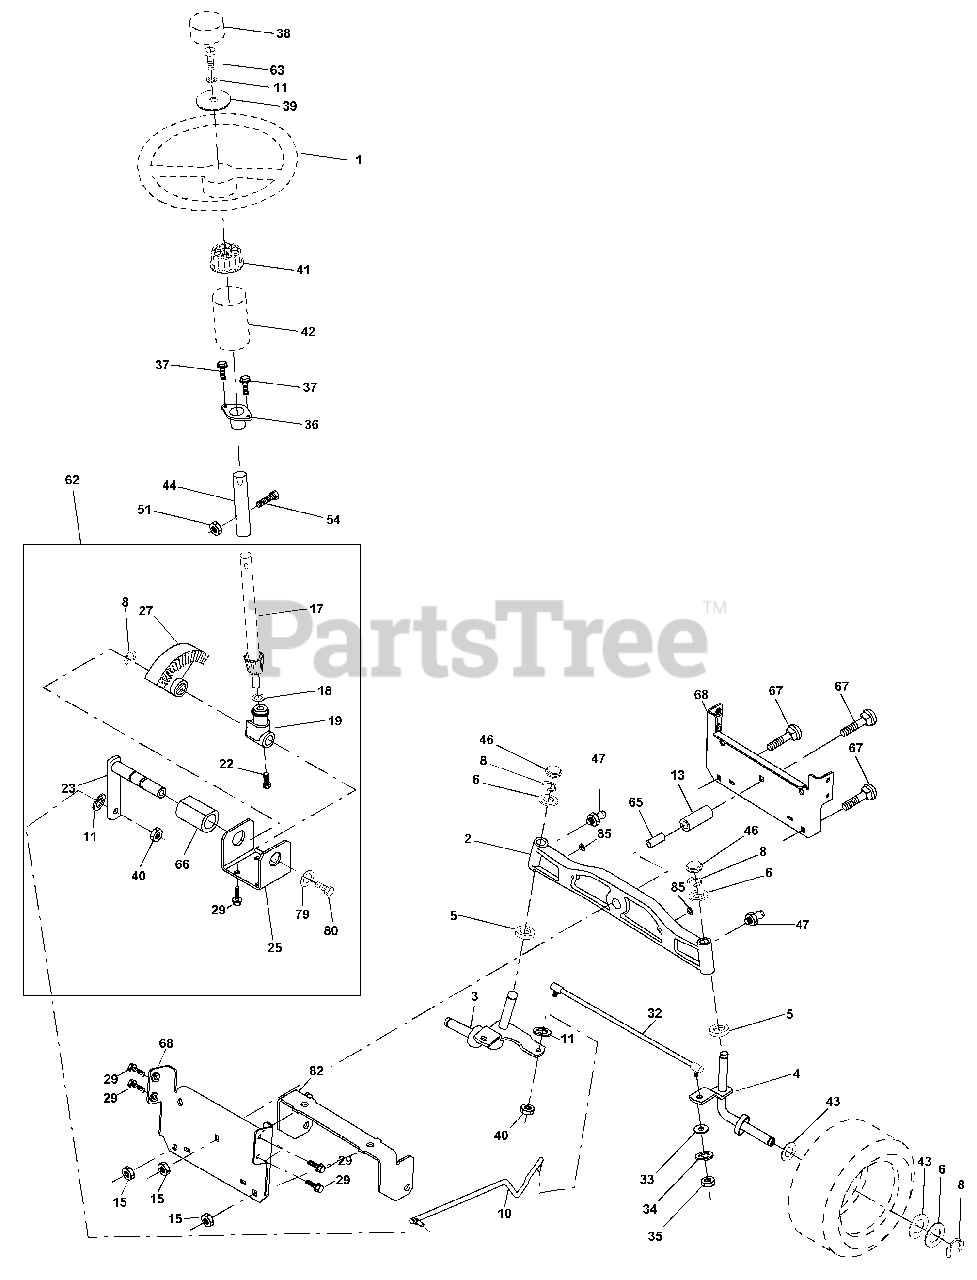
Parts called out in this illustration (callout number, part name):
1	Wheel Steering
2	Axle Cast Lt Machined
3	Spindle Asm LH
4	Spindle Asm RH
5	Bearing Race Thrust Harden
6	Washer 25/32 X 1-5/8 X 16 Ga
8	Ring Klip #t5304-75
10	Link Drag
11	Washer Lock Hvy Hlcl Spr 3/8
13	Spacer Brg Axle Front
15	Nut Hex Flange Lock
17	Shaft Asm Strg Private Label
18	Washer Thrust 515 x 750 x 033
19	Support Shaft
22	Screw Hex Wsh Hd Torx
23	Shaft Asm Pittman
25	Bracket Steering
27	Gear Sector 22 Teeth
29	Screw 3/8-16 x 3/4
32	Rod Tie
33	Washer 11/32 x 3/4 x 16 Ga.
34	Washer Lock Hry Hlcl Spr 5/16
35	Nut Crownlock 5/16 - 24 UNF
36	Bushing Strg
37	Screw TT #32.5 x 5 x 3/8 Flange
38	Cap Wheel Steer
39	Washer 13/32 x 1-1/20 x 11 Ga
40	Nut Lock Center 3/8-24 Unf
41	Adaptor Wheel Strg
42	Boot Dash Steering
43	Washer 25/32 X 1 1/4 X 16 Ga
44	Extension Steering Non-adjust
46	Cap Spindle Fr Top Blk
47	Fitting Grease
51	Nut Lock Hex W/Ins 5/16-18 UNC
54	Bolt Fin Hex 5/16-18 UNC x 1-1/4
62	Steering Assembly
63	Bolt Fin Hex 3/8-16 UNC x 1 Gr. 5
65	Spacer Brace Axle
66	Bearing Arm Pittman
67	Bolt Rdhd Sqn 3/8-16 x 2-1/4
68	Brace, Axle
79	Washer 13/32 x 1-1/4 x 12 Ga.
80	Bolt Hex Nylon 3/8-16 x 3/4
82	Bracket Susp Chassis Front
85	Fastner Christmas Tree
